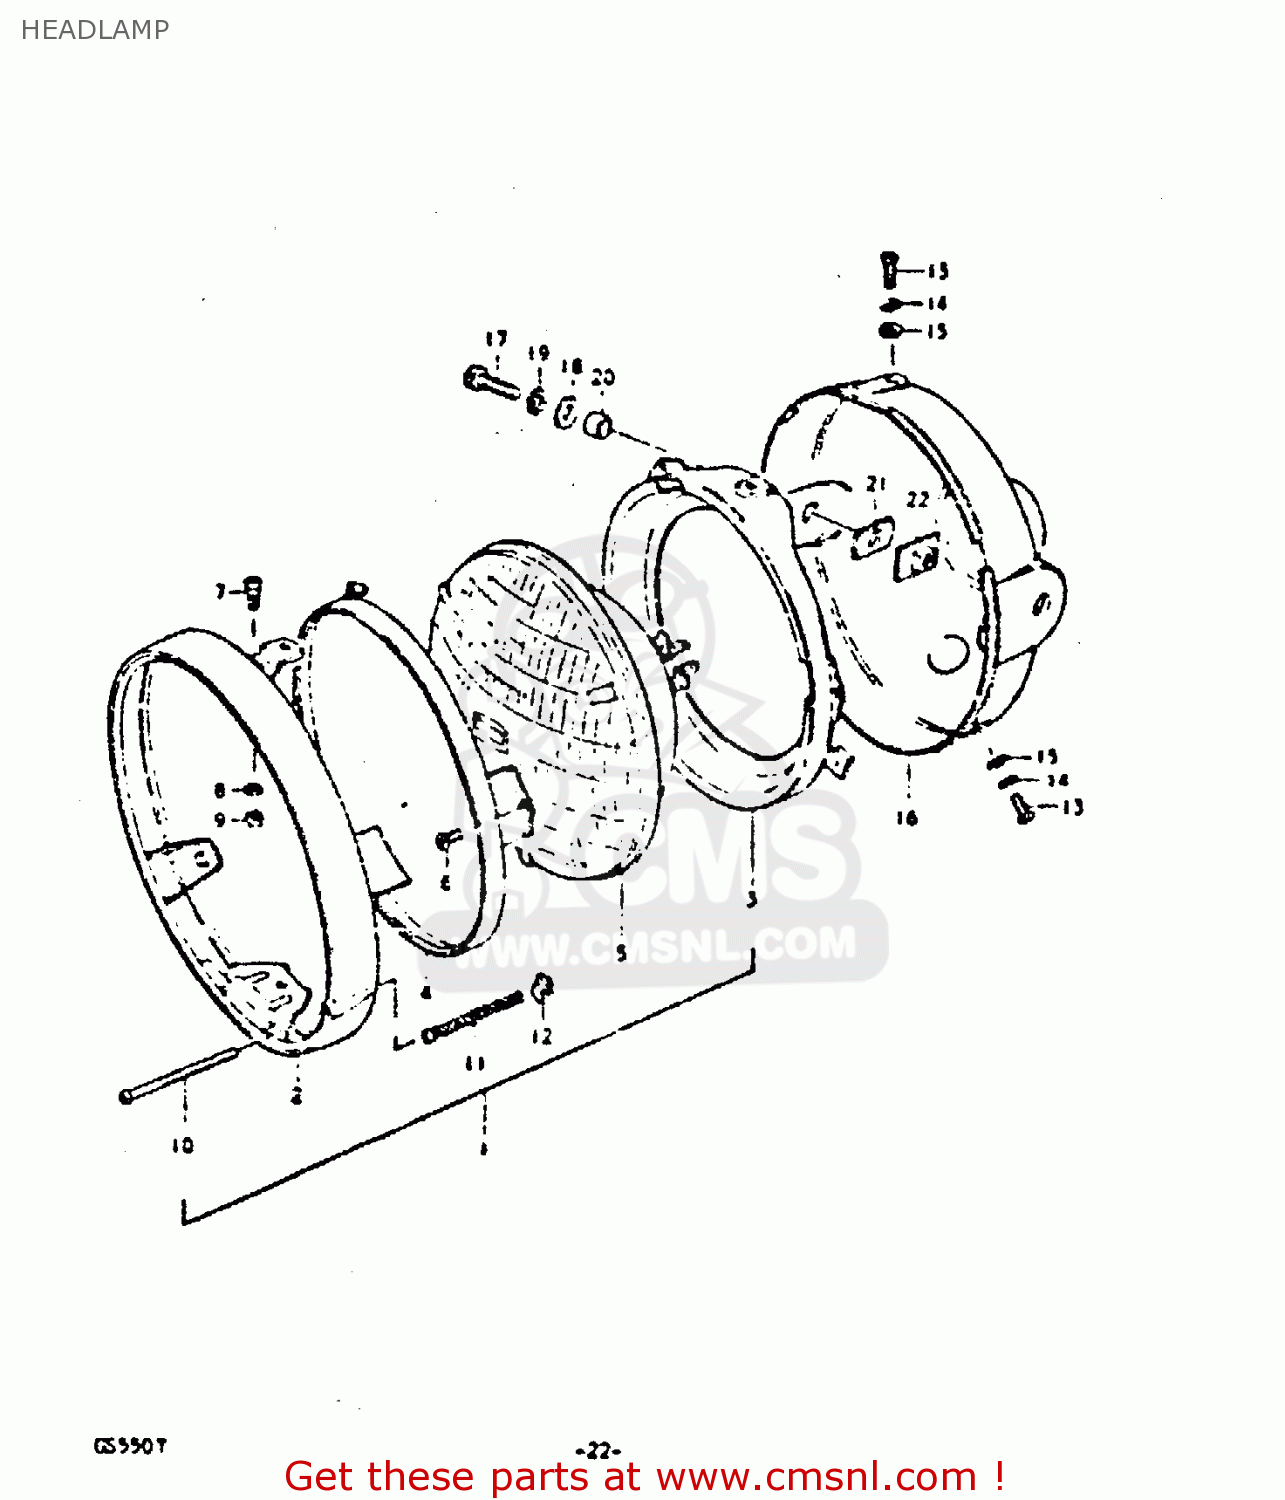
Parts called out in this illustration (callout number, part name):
1	HEADLAMP ASSY
2	RIM
3	RING
4	RETAINING RING
5	UNIT
6	SCREW
7	H/LAMP LENS UNIT FITING SCRE
8	LOCK WASHER
9	NUT
10	SCREW,HEADLAMP ADJUST
11	SPRING,ADJUSTING
12	NUT
13	SCREW
14	WASHER,LOCK
15	WASHER
16	HOUSING,HEADLAMP(BLACK)
17	BOLT
18	WASHER
19	LOCK WASHER
20	SPACER (8.8X12X7)
21	CUSHION
22	PLATE,HEADLAMP HOUSING
